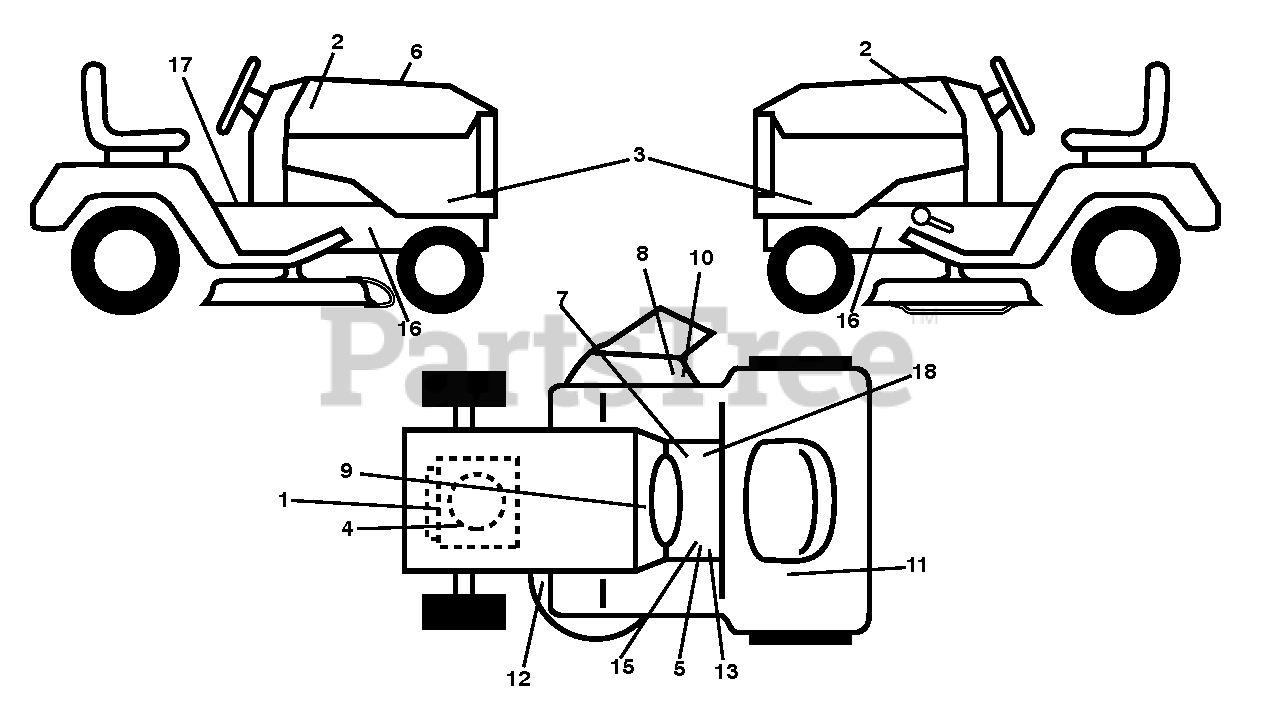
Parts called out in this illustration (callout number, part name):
1	DECAL, ENG. HP
2	RP.DECAL.BADGE.170MM.TEXTLOGO
3	DECAL DECAL.SDPNL.GT2.YTH2246
4	DECAL
5	DECAL 80 DBA
7	DECAL
8	DECAL.INTERNATIONL.CUTFINGER
9	DECAL BTRY SYMBOLS
10	DECAL, DEFLECT WARNING
11	DECAL.WARN.RESERVE.FUEL
12	DECAL V BELT SCHEMATIC
13	LABEL
15	DECAL
17	DECAL PARK BRAKE
18	DECAL
